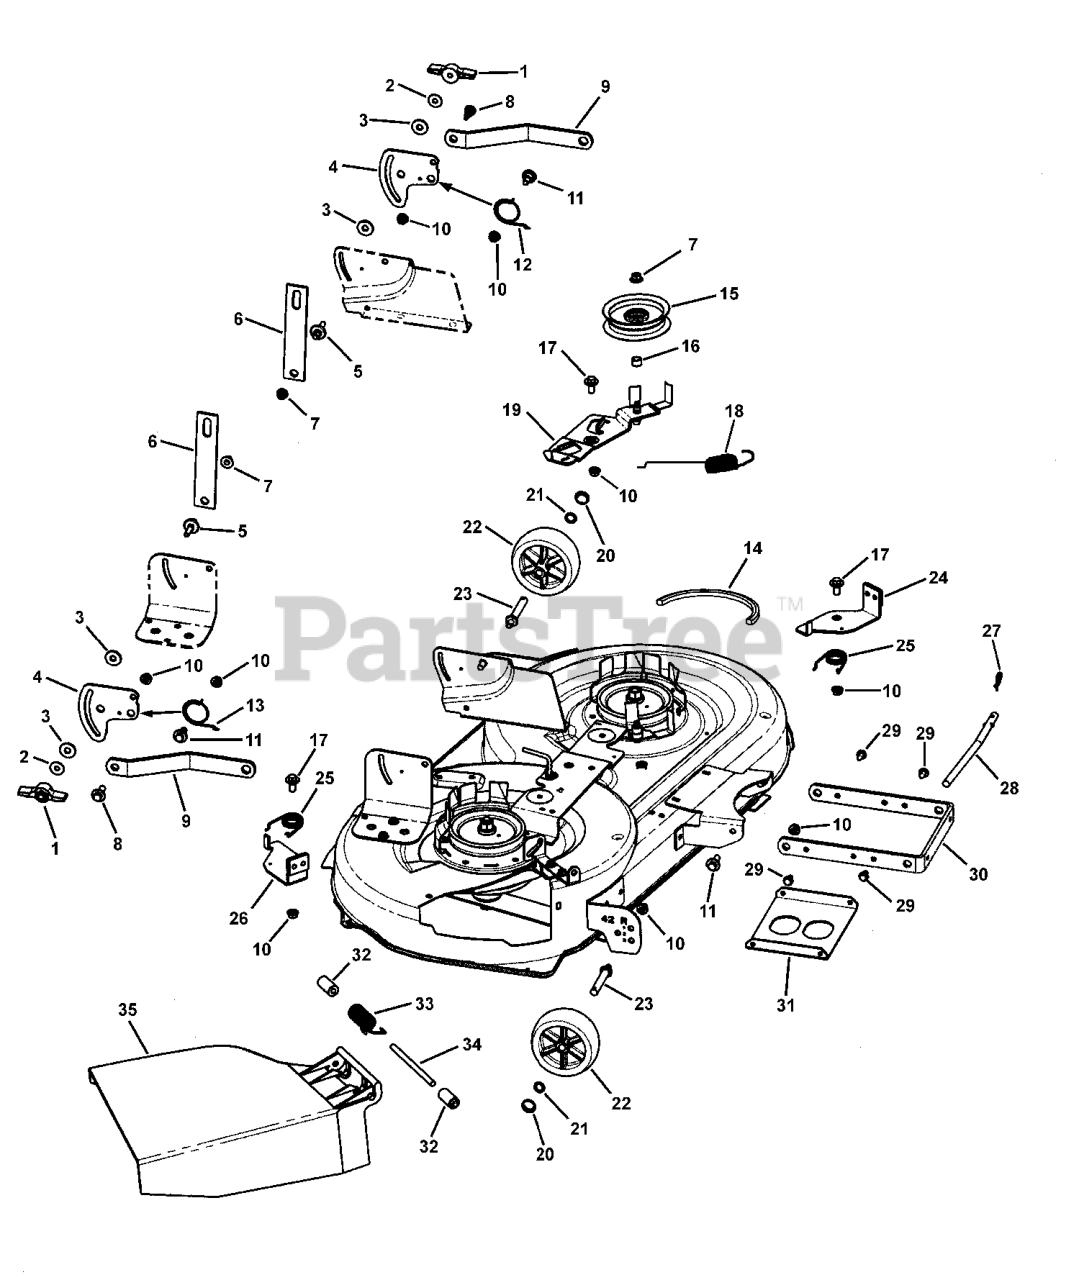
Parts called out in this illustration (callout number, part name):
1	KNOB
2	HER FLAT, 1.0 X .328 X 16GA
3	FRICTION PAD
4	PLATE SUSPENSION
5	PIN - HANGER 3/8-16 X 1.25
6	LINK - LIFT (LT)
7	NUT FLANGE, 3/8-16 ZINC PLATED
8	SHOULDER BOLT, 3/8-16 X .600OD X.95L
9	BRACKET SUSPENSION
10	NUT, HEX FLANGE, 3/8-16 NC
11	SHOULDER BOLT, 3/8-16X1.06
12	SPRING, TORSION LH
13	SPRING, TORSION RH
14	BELT, MOWER DRIVE
15	PULLEY BACKSIDE IDLER, 4.0 OD
16	SPACER 1/2" TO 17MM
17	SHOULDER BOLT, 0.75 X 0.60 X 3/8-16
18	SPRING EXTENSION, 9.43L X 0.62D
19	ASSY-IDLER ARM, 42"
20	CLIP - HAIR PIN
21	HER, FLAT, .81 X .550 X 16GA
22	WHEEL GAGE
23	BOLT, Gauge Wheel
24	ASSY-BRAKE L.H.
25	SPRING, TORSION BRAKE
26	ASSY-BRAKE R.H.
27	HAIR PIN, .56D-.092T
28	ROD HANGER
29	CAPSCREW 5/16-18
30	BRKT SUSPENSION FRONT
32	CAP, PUSH ON
34	ROD, Deflector
35	ASSY, DEFLECTOR
